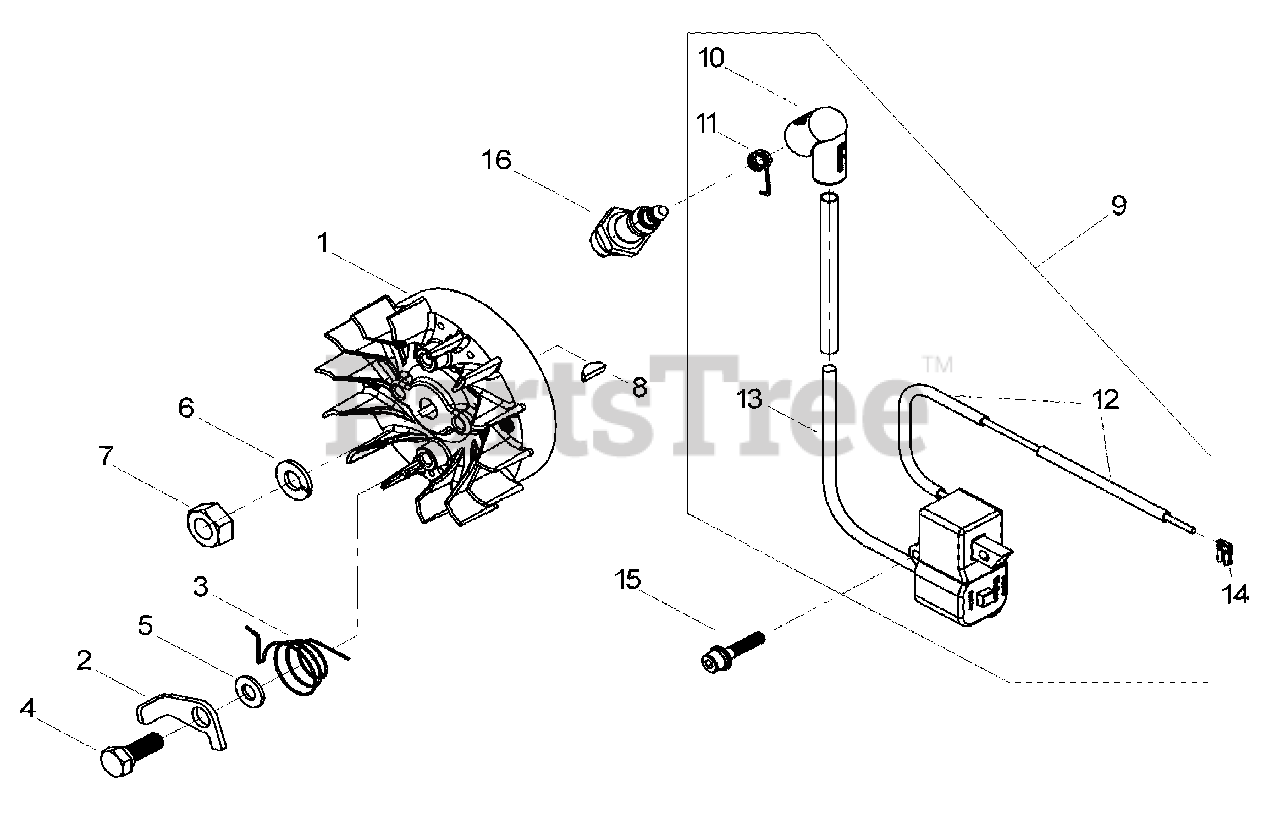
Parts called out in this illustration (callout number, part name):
1	ROTOR
2	PAWL, STARTER
3	SPRING, RETURN
4	BOLT
5	WASHER
6	LOCKWASHER - 8
7	NUT
8	KEY - 3X10
9	IGNITION COIL ASSY
10	CAP, SPARK PLUG
12	TUBE
14	CONNECTOR
15	SCREW - 4X20
16	SPARK PLUG -- BPMR-7A
